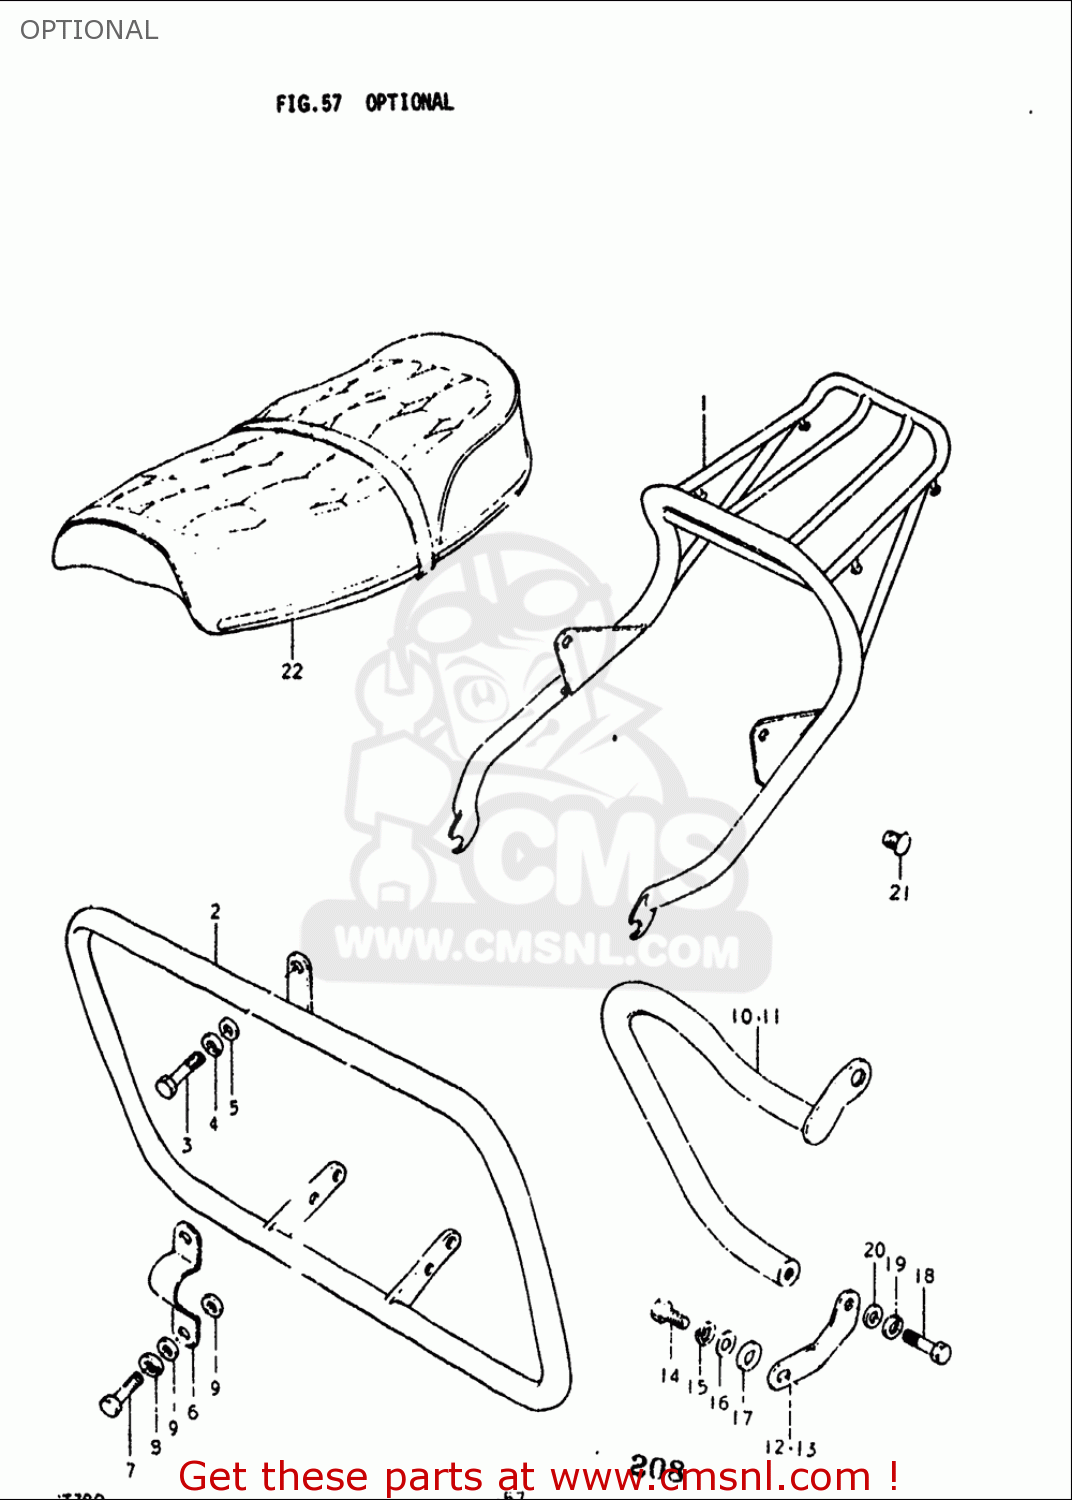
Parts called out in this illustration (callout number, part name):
3	BOLT
4	WASHER,LOCK
5	WASHER
7	BOLT
8	WASHER,LOCK
9	WASHER
14	BOLT
15	WASHER,LOCK
16	WASHER
17	WASHER(12.5X24X3.2)
18	BOLT
19	WASHER,LOCK
20	WASHER
21	CAP(OD:14)
